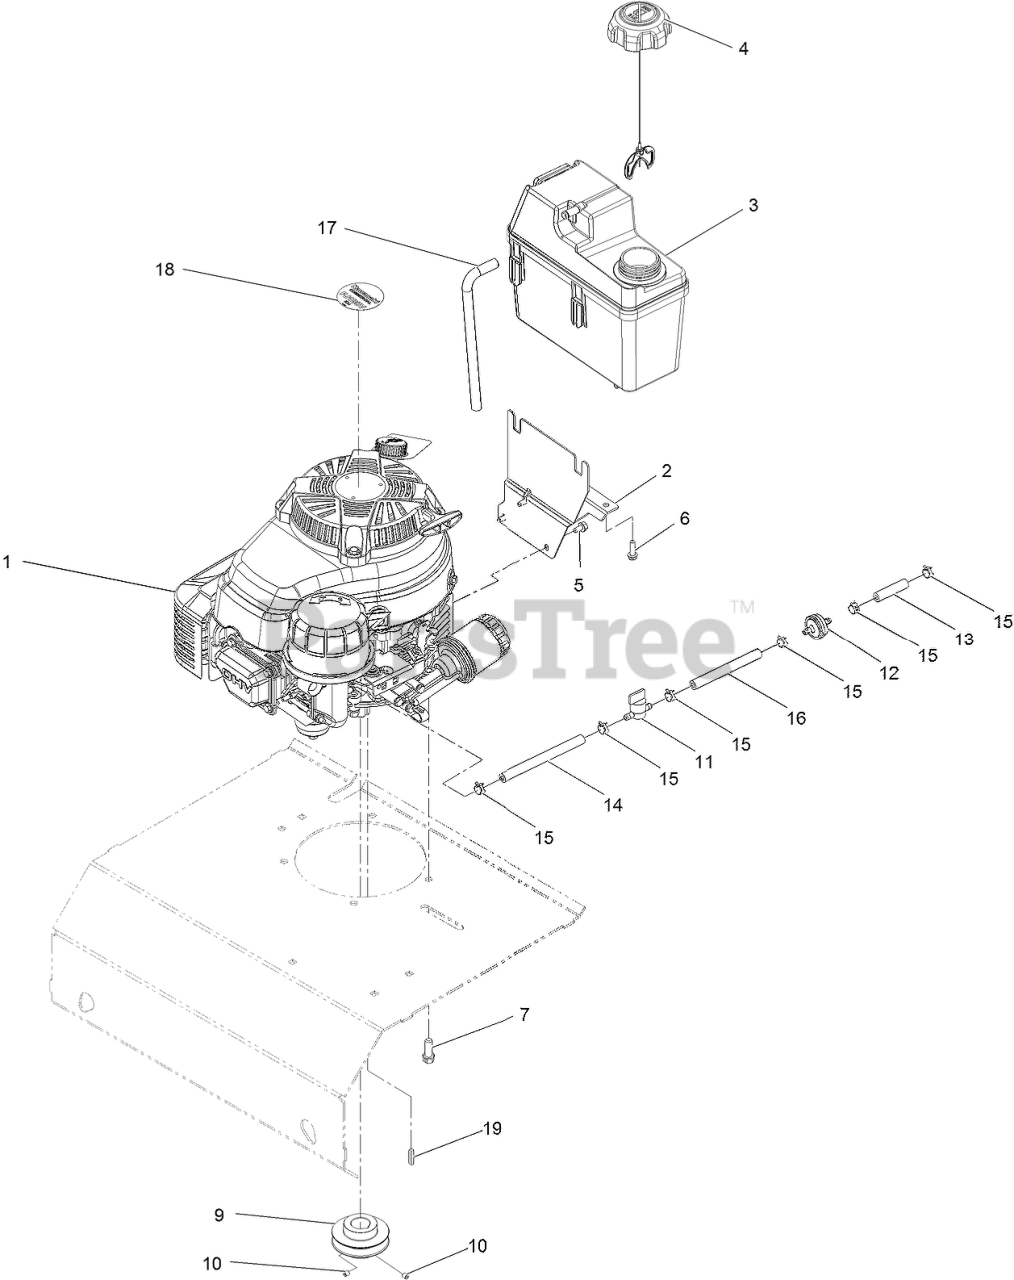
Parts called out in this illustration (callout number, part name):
2	MOUNT-TANK
3	TANK-FUEL
4	CAP-FUEL
5	SCREW-HWH
6	SCREW-HWH
7	SCREW-TAPTITE
9	PULLEY-DRIVER
10	SCREW-SET, HSH
11	VALVE-FUEL
12	Filter-Fuel
13	HOSE-FUEL
14	HOSE-FUEL
15	CLAMP-HOSE
16	HOSE-FUEL
17	HOSE-VENT, CANISTER
